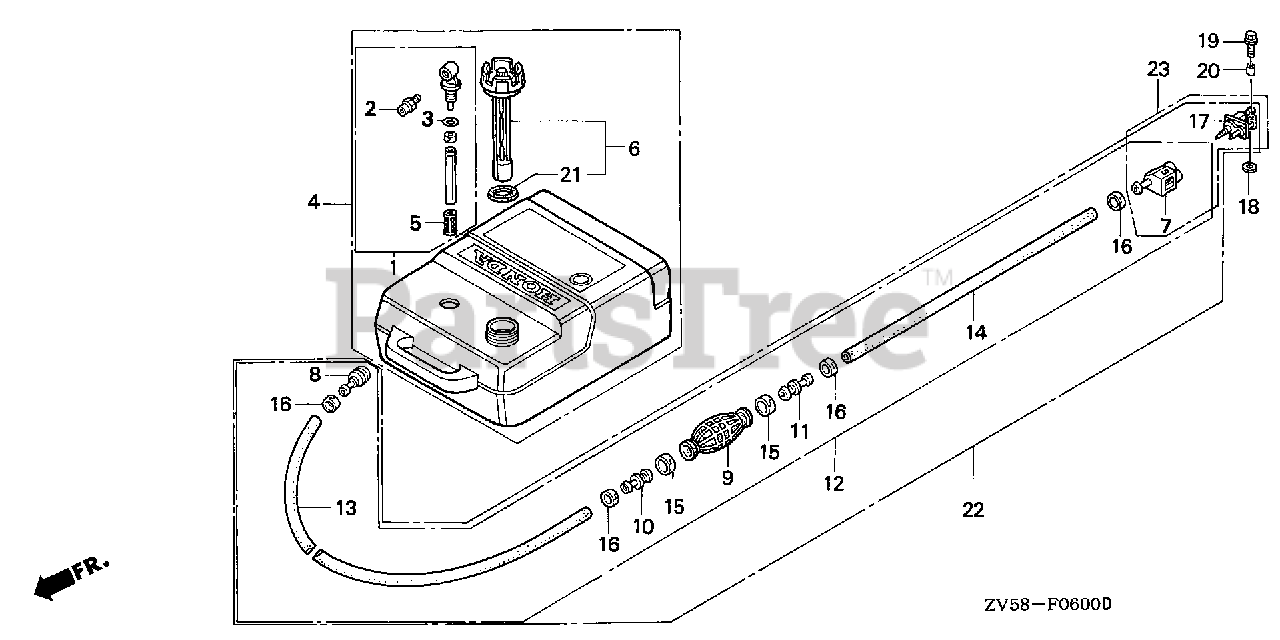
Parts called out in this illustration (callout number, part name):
7	CONNECTOR ASSY., FUEL (A)
8	CONNECTOR, FUEL (CONNECTOR TYPE)
9	BULB, PRIMER
10	VALVE, IN.
11	VALVE, OUTLET
12	TUBE ASSY., FUEL
13	TUBE, FUEL LONG (7.3X2000) (CONNECTOR TYPE)
14	TUBE, FUEL SHORT (6.3X500) (CONNECTOR TYPE)
15	BAND, TUBE CLIP (20MM)
16	BAND, TUBE CLIP (12.5MM)
17	CONNECTOR ASSY., FUEL (B)
18	WASHER, PIVOT
19	BOLT, FLANGE (6X20)
20	COLLAR, DISTANCE (6MM)
